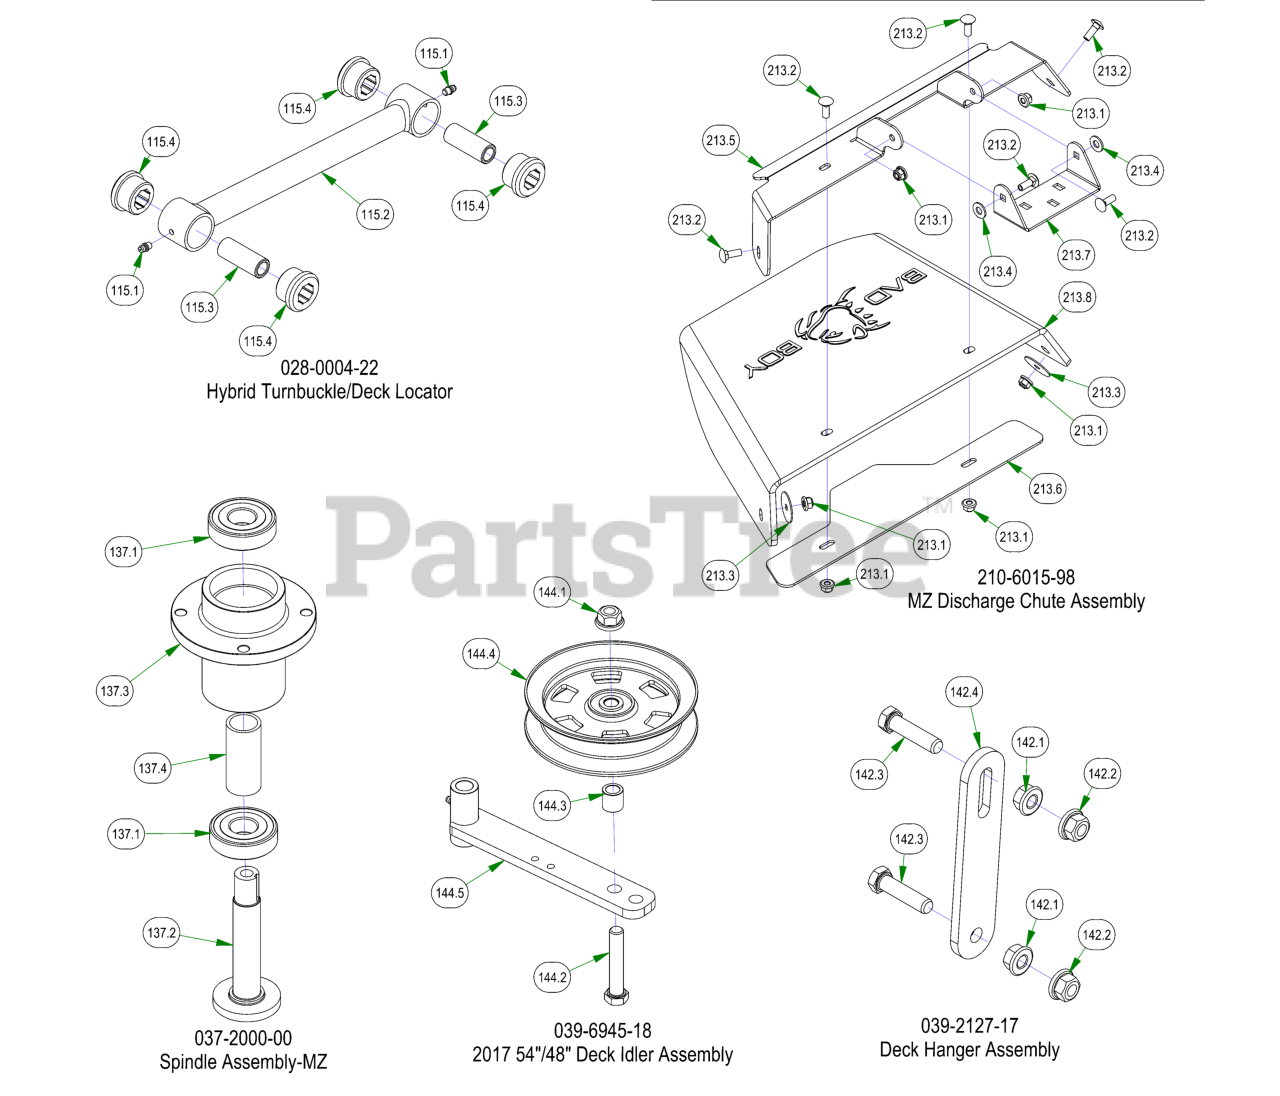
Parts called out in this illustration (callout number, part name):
115	Hybrid Turnbuckle/Deck Locator
115.1	1/4-28 Grease Fitting
115.2	2022 Isolator Turnbuckle Body
115.3	2018 Maverick Bushing Sleeve
115.4	2018 Maverick Bushing
137	Spindle Assembly-MZ
137.1	Spindle Bearing
137.2	Spindle Shaft
137.3	Spindle Housing
137.4	Spindle Spacer-Component
142	Deck Hanger Assembly
142.1	3/8-16 HEX SERRATED FLANGE NUT HARD/ZINC
142.2	3/8-16 NYLON INSERT FLANGE LOCKNUT (GR.F) ZINC
142.3	3/8-16 X 1-1/2 HEX CAP SCREW (GR.5) ZINC
142.4	2017 MZ/ZT Deck Hanger
144	2017 54"/48" Deck Idler Assembly
144.1	1/2-13 NYLON INSERT FLANGE LOCKNUT ZINC
144.2	1/2-13 X 2-3/4 HEX CAP SCREW (GR.5) ZINC
144.3	.51 ID X .75 OD X .75 LGTH SOLID SPACER ZINC
144.4	5" Idler Pully
144.5	Deck Idler
213	MZ Discharge Chute Assembly
213.1	5/16" Nylon Flange Nut
213.2	5/16" x 7/8" Carriage Bolt
213.3	5/16 Fender Washer
213.4	.360 ID Plastic Washer
213.5	Discharge Chute Bracket 48 MZ (Upper)
213.6	2017 MZ Discharge Chute Bracket-Lower
213.7	Chute Hanger 48 MZ
213.8	Rubber Discharge Chute MZ (Component)
